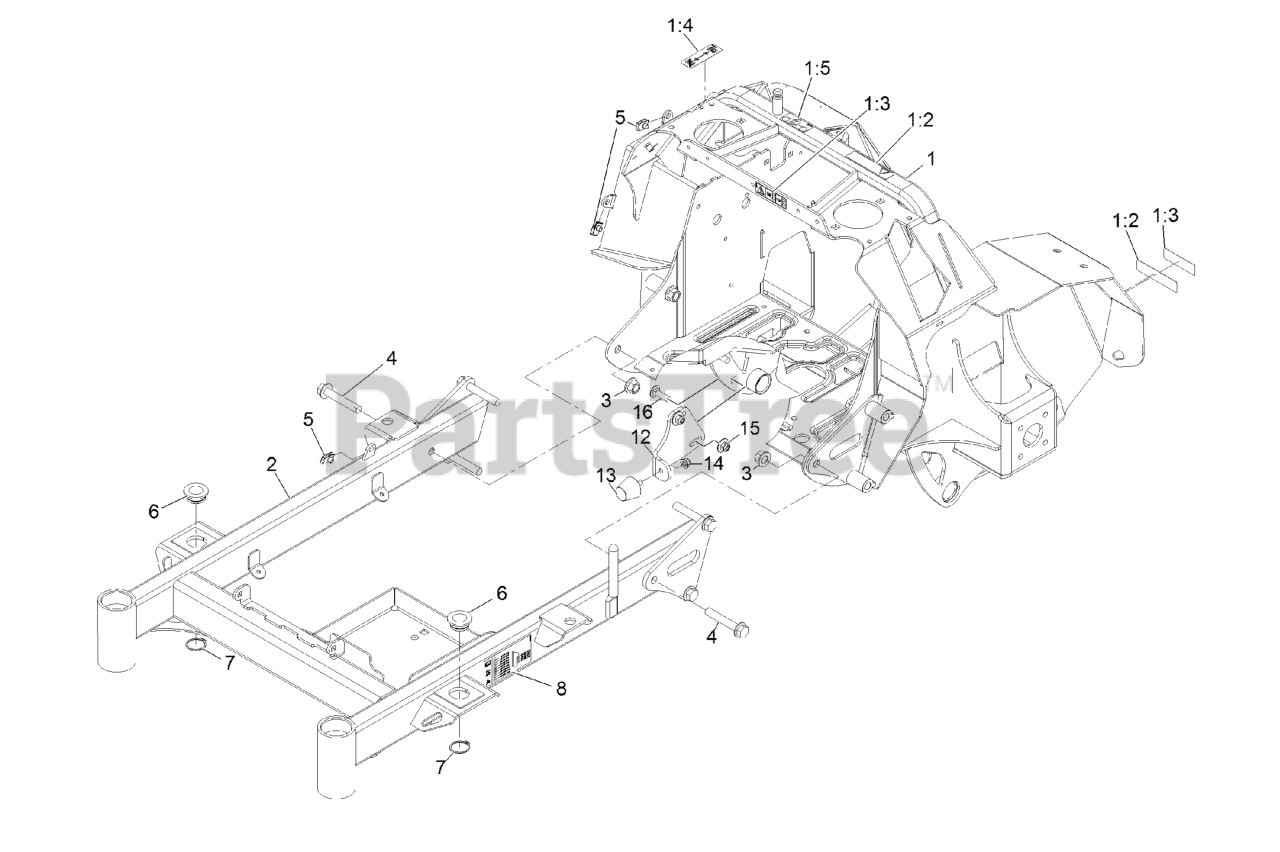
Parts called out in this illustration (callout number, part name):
1	ASM-FRAME
1:2	DECAL-WARNING
1:3	DECAL, COVER MISSING
1:4	DECAL-BRAKE, PARKING
1:5	DECAL-BELT ROUTING HYD
2	ASM-FRT FRAME 32/36
3	Nut-Lock 1/2-13
4	SCREW-HF
6	BUSHING-DECK
7	RING-RETAINING
8	DECAL-HEIGHT OF CUT SM
12	BRACKET-BUMPER
13	BUMPER-RUBBER
14	NUT-HF, NI
15	Nut-Nyloc 3/8-16 Flg
16	BOLT-CARR
